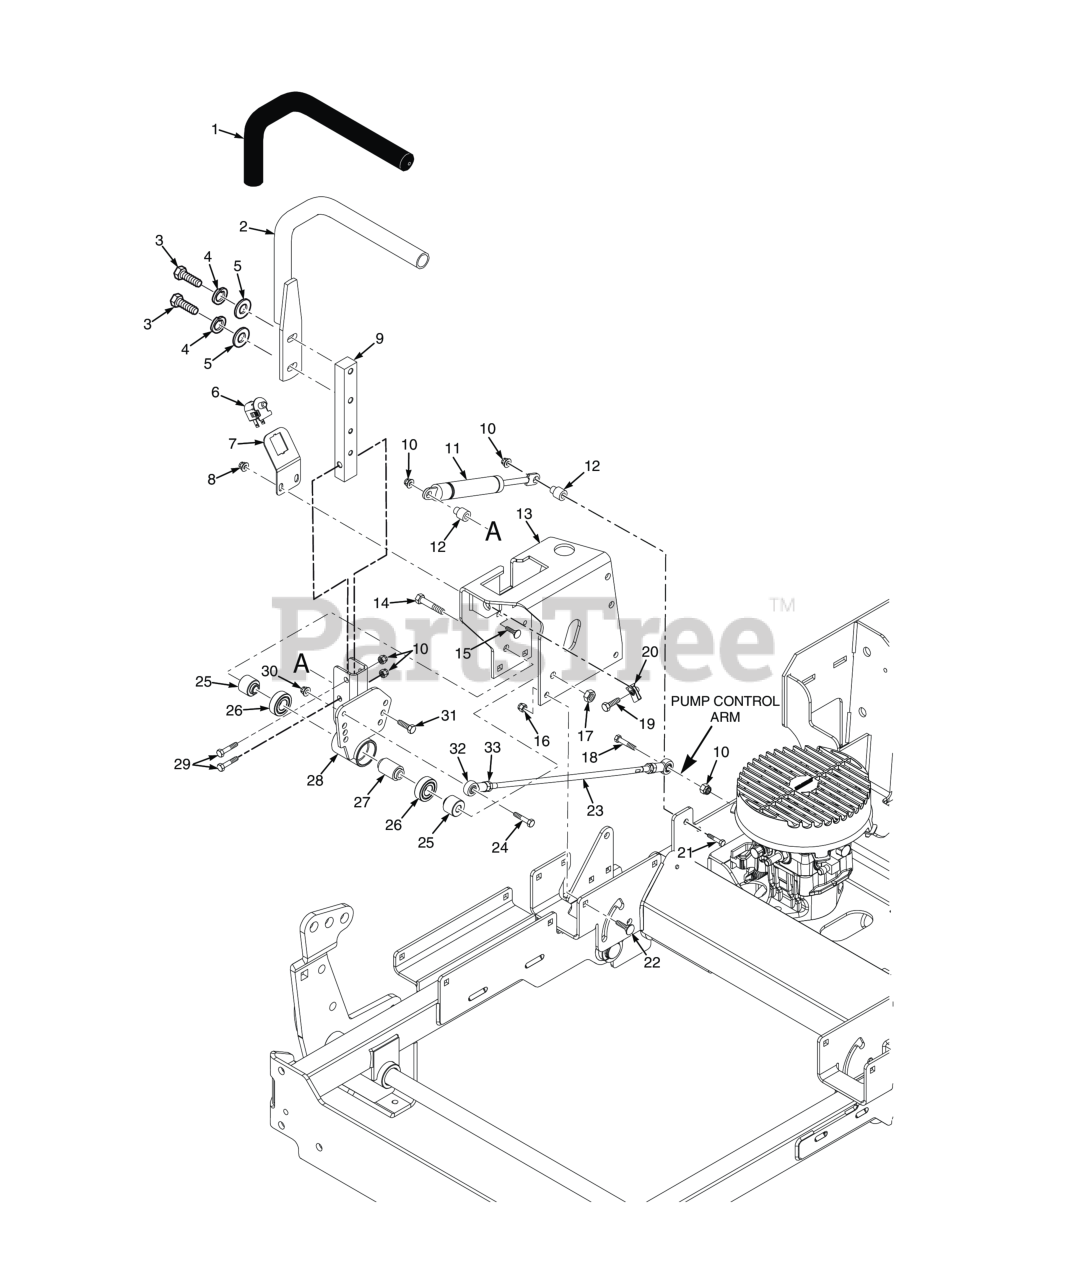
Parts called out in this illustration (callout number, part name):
1	Grip, Control Handle
2	Handle Bar w/Grip
3	Bolt, Hex Head 3/8-16 x 1-1/4", Kawasaki FX / FS
4	Lockwasher, 3/8" Spring, Kawasaki FX / FS
5	Flatwasher, 3/8" Special (.391 x .938 x .105)
6	Switch, Interlock, Normally Open
7	Bracket, Operator Presence Switch
8	Nut, Flanged Elastic Stop 1/4-20
9	Bar, Control Lever
10	HEX NUT, ELASTIC STOP LOCK, 5/16-18
11	Gas Damper
12	Spacer, Pump Dampener
13	Control Plate w/decal, LH
13	Control Plate w/decal, RH
14	Bolt, Hex Head 3/8-16 x 4-1/4"
15	Serr. Fl. Hex Head CPSCR, 1/4-20 x 3/4"
16	Nut, Serrated Flange 5/16-18 (Right Front Engine Mounting, Briggs and Kohler Only)
17	Bolt, Hex Head 3/8-16 x 1" Ser. Flg.
18	Bolt, Heax Head 5/16-18 x 1" (48V / 52V)
19	Bolt, Hex Head 3/8-16 x 1-1/4" with Thread Lock Patch
20	U-Nut, 3/8-16 (short)
21	Bolt, Hex Head 5/16-18 x 1-1/2" (Right Front Engine Mounting, Briggs and Kohler Only)
21	Bolt, Hex Head 5/16-18 x 1-1/2" - Front
22	Bolt, 5/16-18 x .75 RHSN Carriage
23	Linkage Assy, Steering
23	Rod End, 5/16-24 LH
23	Nut, Jam 5/16-24 UNF-2B
24	Bolt, Hex Head, 1/4-20 x 1-1/2"
25	Spacer, Controls
26	BEARINGS, BALL, NEUTRAL RETURN
27	Spacer, Bearing
28	Pivot Weldment, Control Arm RH
28	Pivot Weldment, Control Arm LH
29	Bolt, Hex Head 5/16-18 x 1-1/2" - Front
30	HEX, NUT, ELASTIC STOP LOCK, 1/4-20
31	Bolt, Hex Head 5/16-18 x 1-1/2" (Right Front Engine Mounting, Briggs and Kohler Only)
32	Rod End, 5/16-24 RH
33	Nut, 5/16-24 UNF Jam LH
